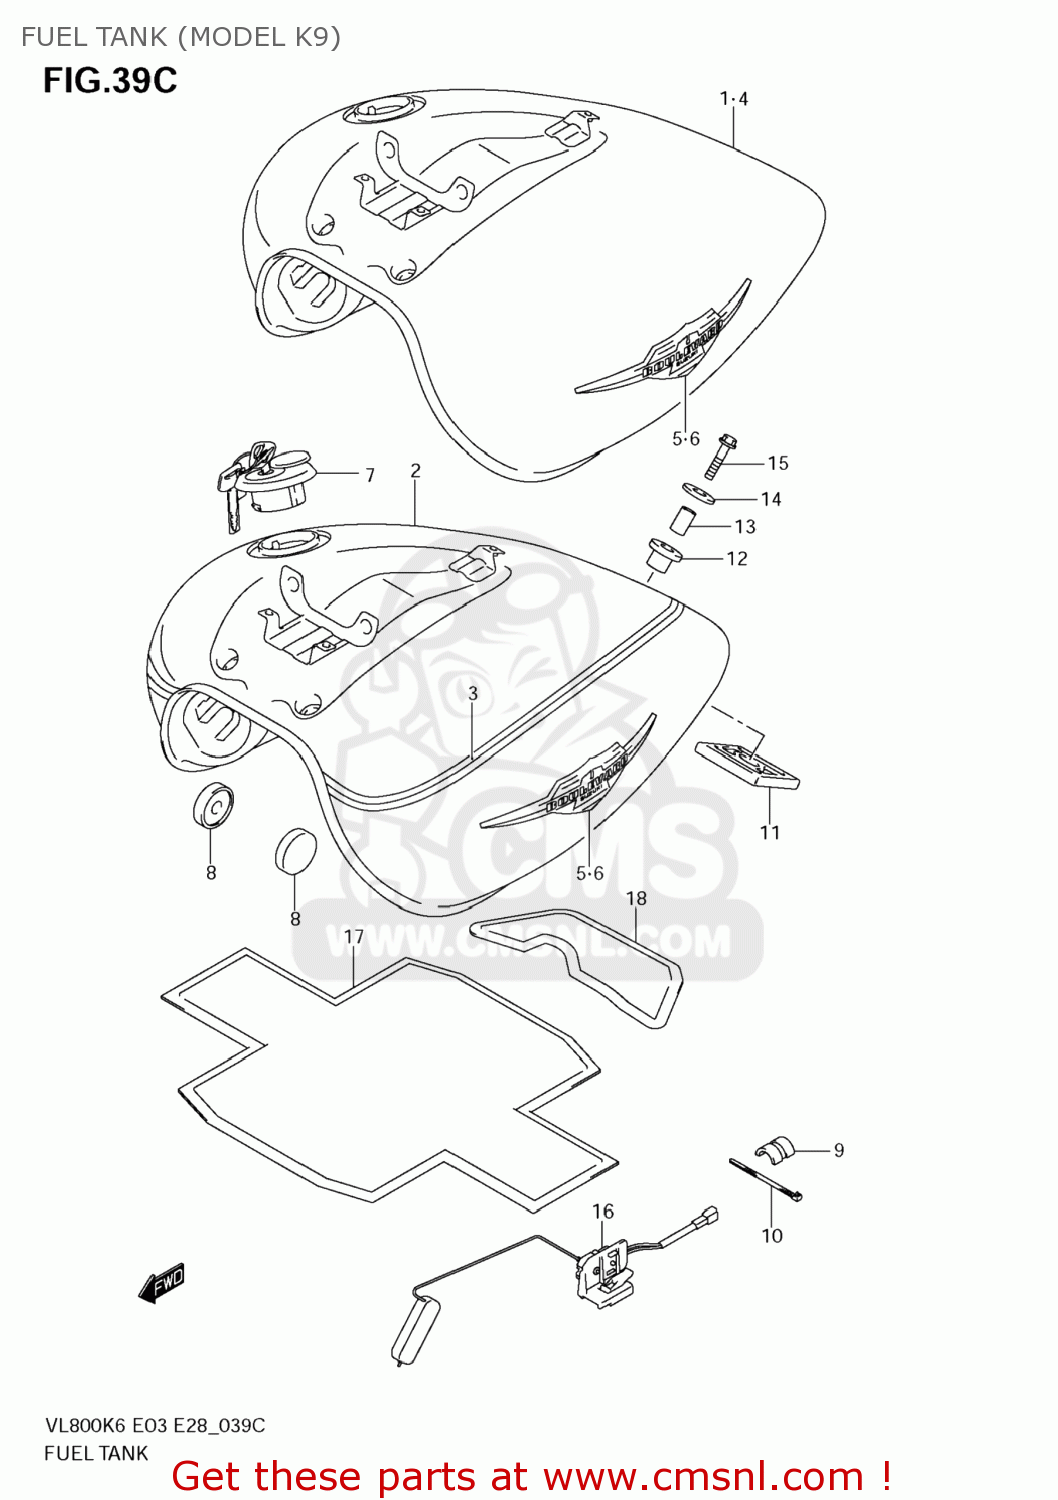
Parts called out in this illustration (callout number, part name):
1	TANK ASSY,FUEL(RED)
2	TANK ASSY,FUEL
3	TAPE SET,FUEL TANK
4	TANK ASSY,FUEL(GRAY)
5	EMBLEM,FUEL TANK,R
6	EMBLEM,FUEL TANK,L
7	CAP SET,FUEL TANK
8	CUSHION
9	CUSHION,FUEL TANK LWR
10	CLAMP(L:250)
11	CUSHION,FUEL TANK RR LWR
12	CUSHION,FUEL TANK RR UPR
13	SPACER (8.2X12.5X23.5)
14	WASHER(8.5X33X1.5)
15	BOLT
16	GAUGE ASSY,FUEL LEVEL SENDER
17	SHIELD,FUEL TANK HEAT
18	SHIELD,FUEL TANK HEAT NO.2
